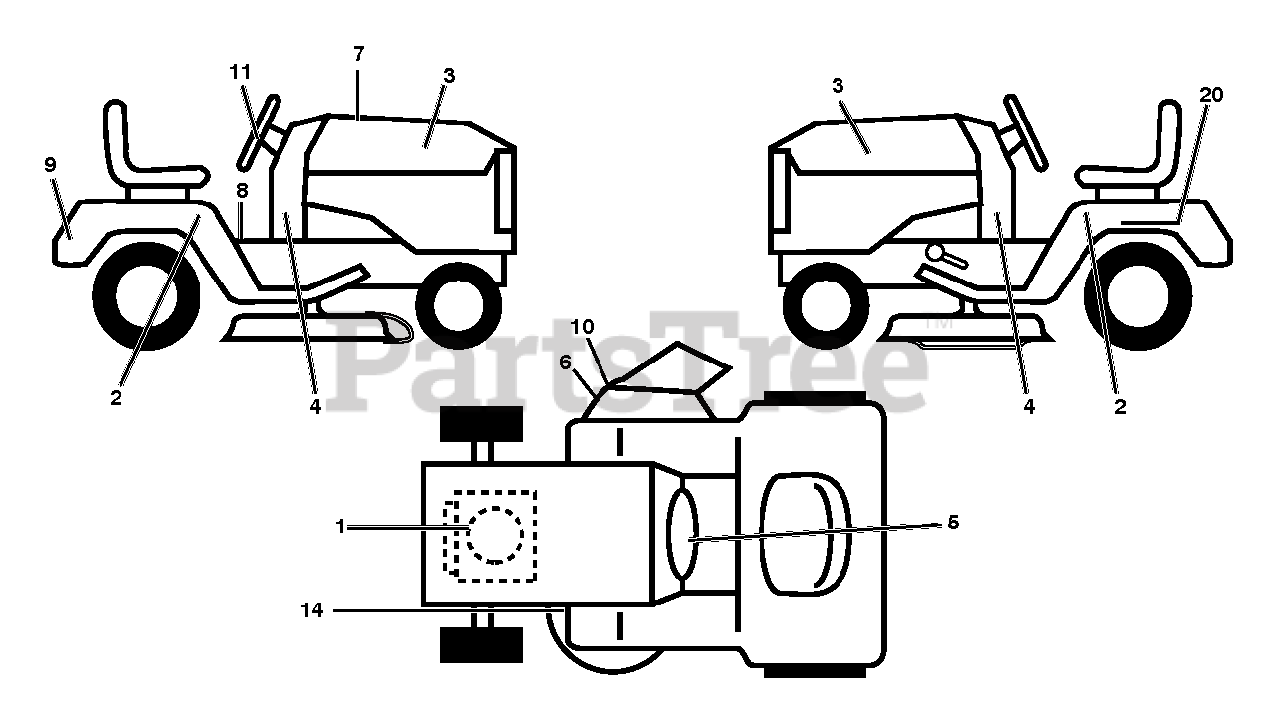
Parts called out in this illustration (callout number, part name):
2	DECAL.FEND.RH/LH.SET.6S.POULAN
3	DECAL.HOOD.ALPHA.RH/LH.POULAN
5	DCL.WARNING.SPARK.IGNITION.CA
6	DECAL.WARN.DFLECT/CTFINGR.SRD
8	DECAL.WARNING.2007.ENG/FR
9	DECAL.FEND.POULAN.2010
10	DECAL.MOWER.WARN.KEEP.HAND.AWY
11	DECAL.WHEEL.STRG.STDHRS.POULAN
14	DECAL.V.BELT.30"
20	DECAL BTRY SYMBOLS
